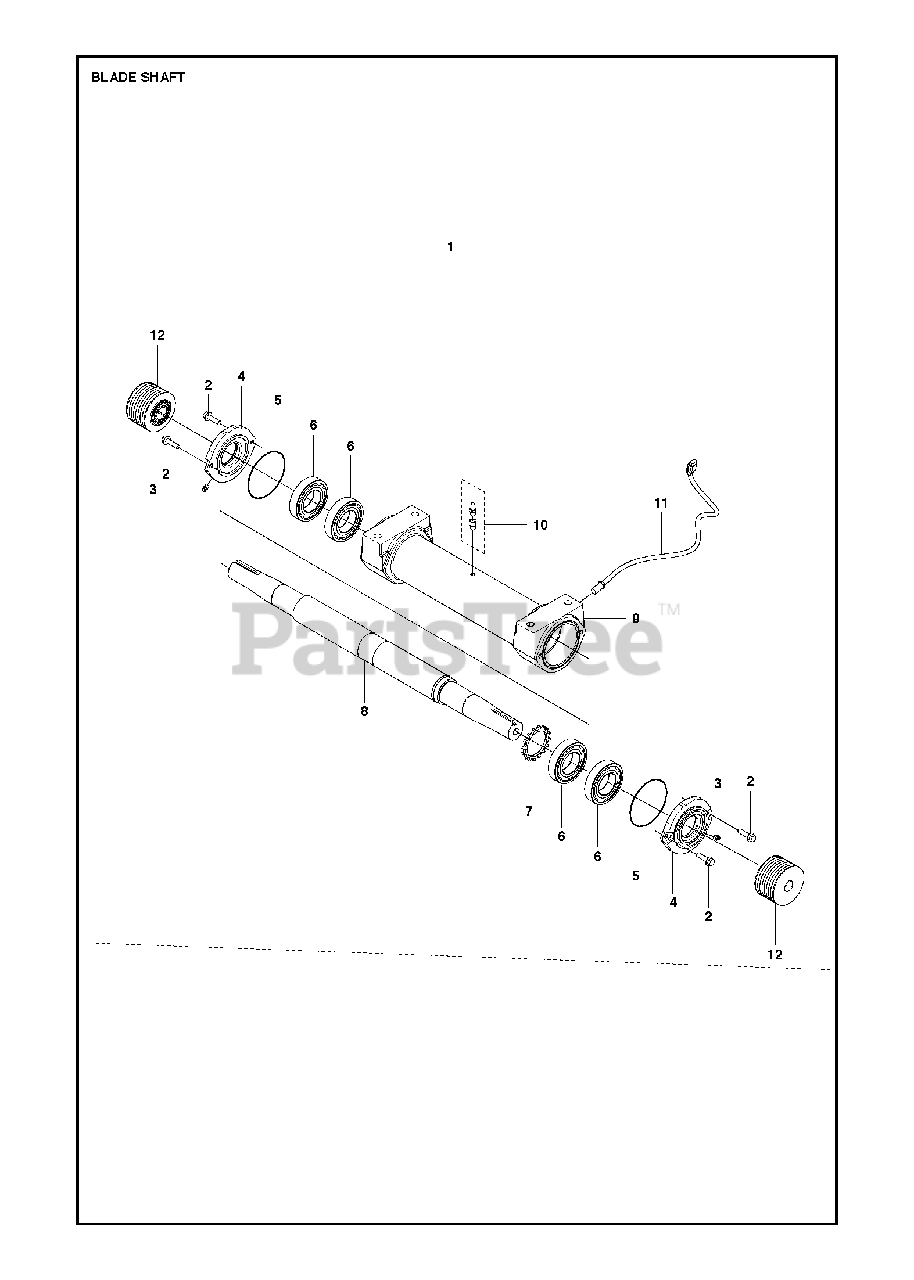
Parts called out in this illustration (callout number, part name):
1	SHAFT ASSY20" 1-speed
1	SHAFT ASSY26" 1&3-speed and 30" 3-speed
1	SHAFT ASSY30" 1-speed
1	SHAFT ASSY36" 1-speed
1	SHAFT ASSY42" 1-speed
1	SHAFT ASSY36" 3-speed
1	SHAFT ASSY42" 3-speed
12	PULLEY20" 1-speed, 26" 1&3-speed and 30" 3-speed
